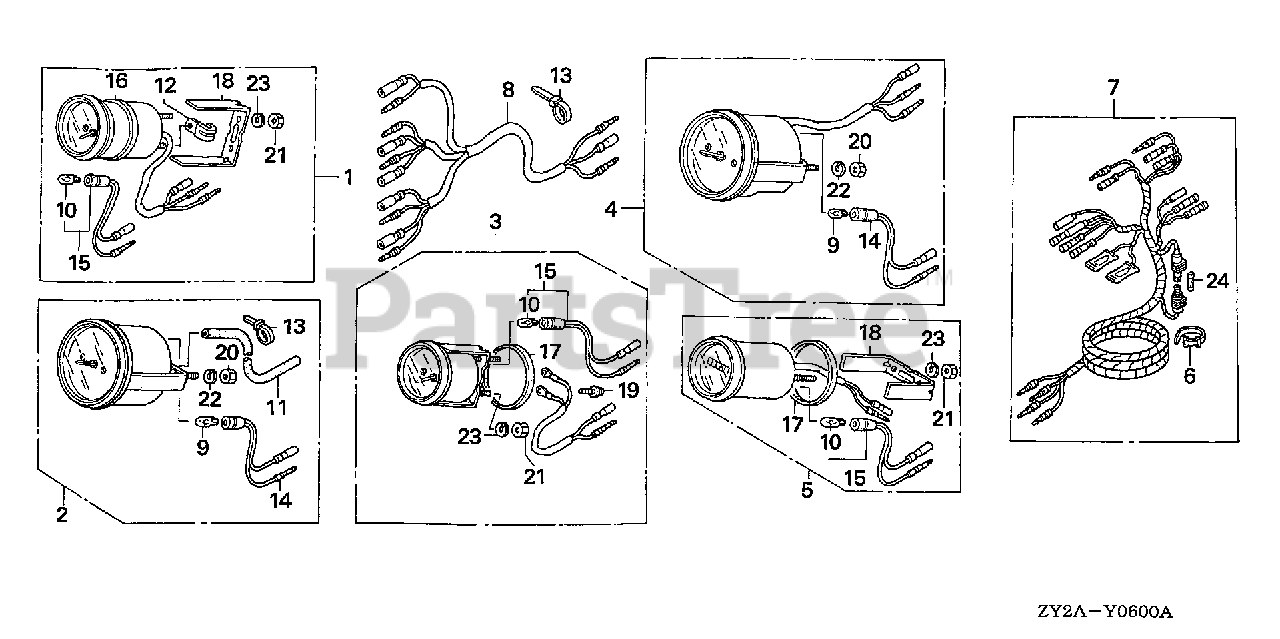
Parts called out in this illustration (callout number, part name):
1	METER KIT, TRIM
1	METER KIT, TRIM (B)
2	SPEEDOMETER KIT
2	SPEEDOMETER KIT (B)
3	METER KIT, VOLT
3	METER KIT, VOLT (B)
4	METER KIT, TACHO
4	METER KIT, TACHO (B)
5	METER KIT, HOUR (NA USE ALT:39700-ZW5-000ZA)
5	METER KIT, HOUR (B) (NA USE ALT:39700-ZW5-000ZA)
6	BAND B1, WIRE
7	HARNESS ASSY., METER (A)
8	HARNESS ASSY., METER (B)
9	BULB, WEDGE BASE (T10) (12V 1.7W) (STANLEY)
10	BULB, WEDGE BASE (12V 1.7W)
11	TUBE, SPEED METER (4X7X8000)
12	CLAMP
13	BAND, SELF-LOCK
14	SOCKET
15	SOCKET
16	GASKET
17	GASKET
18	BRACKET
19	SCREW-WASHER (3X22)
20	NUT, HEX. (5MM)
21	NUT, HEX. (4MM)
22	WASHER, SPRING (5MM)
23	WASHER, SPRING (4MM)
24	FUSE A (10A)
